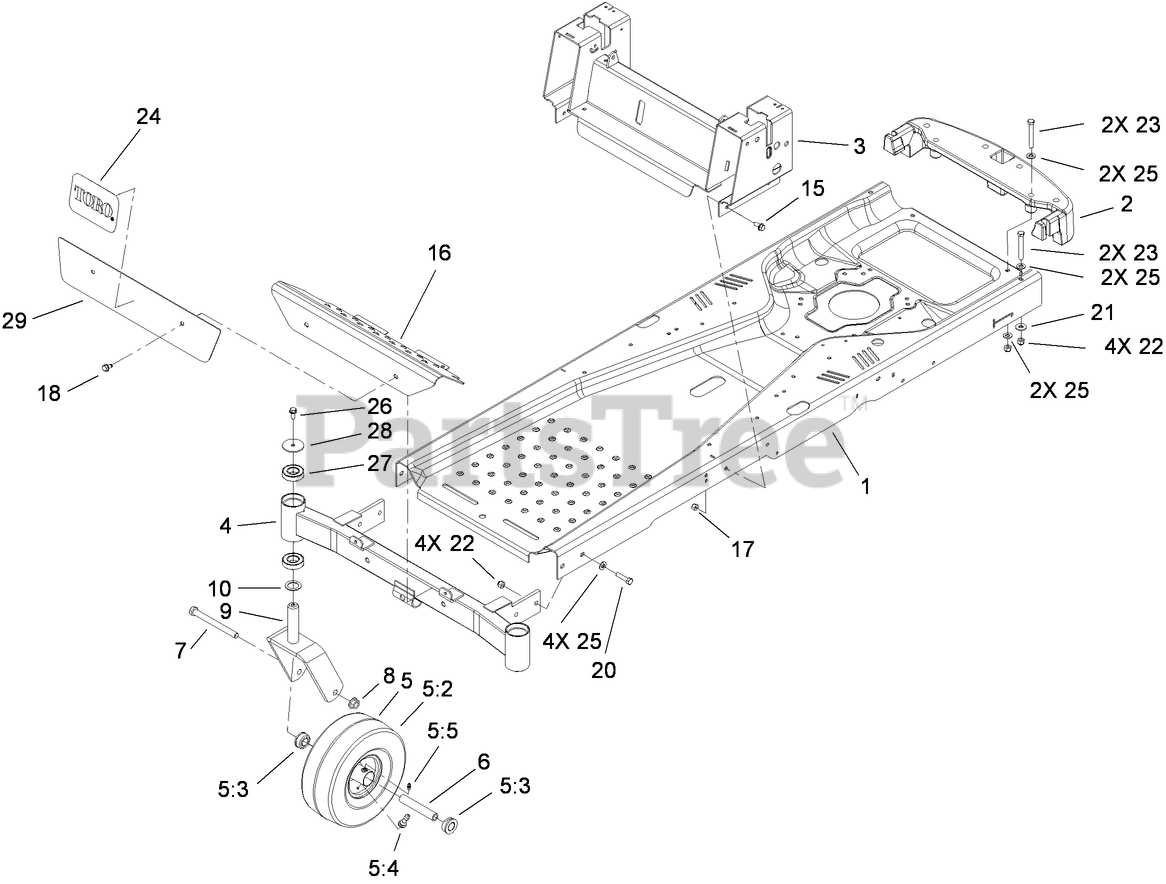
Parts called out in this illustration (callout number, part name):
2	BUMPER-REAR
3	SEAT PIVOT/CONTROL ASM
4	FRONT AXLE ASM
5	TIRE AND WHEEL ASM (KENDA)
5:2	TIRE-SMOOTH
5:3	BUSHING-FLANGE
5:5	FITTING-GREASE
6	BUSHING-SPANNER
7	SCREW-HH
8	NUT-HEX
9	CASTER FORK ASM
10	WASHER-THRUST
15	SCREW-HHF
16	FOOTREST
17	NUT-LOCK, NI
18	SCREW-HWH
20	SCREW-HH
21	WASHER-HARDENED
22	NUT-LOCK, NI
23	SCREW-HH
25	WASHER-FLAT
26	SCREW-HHF
27	BEARING-BALL
28	WASHER
29	PLATE-FOOTREST
